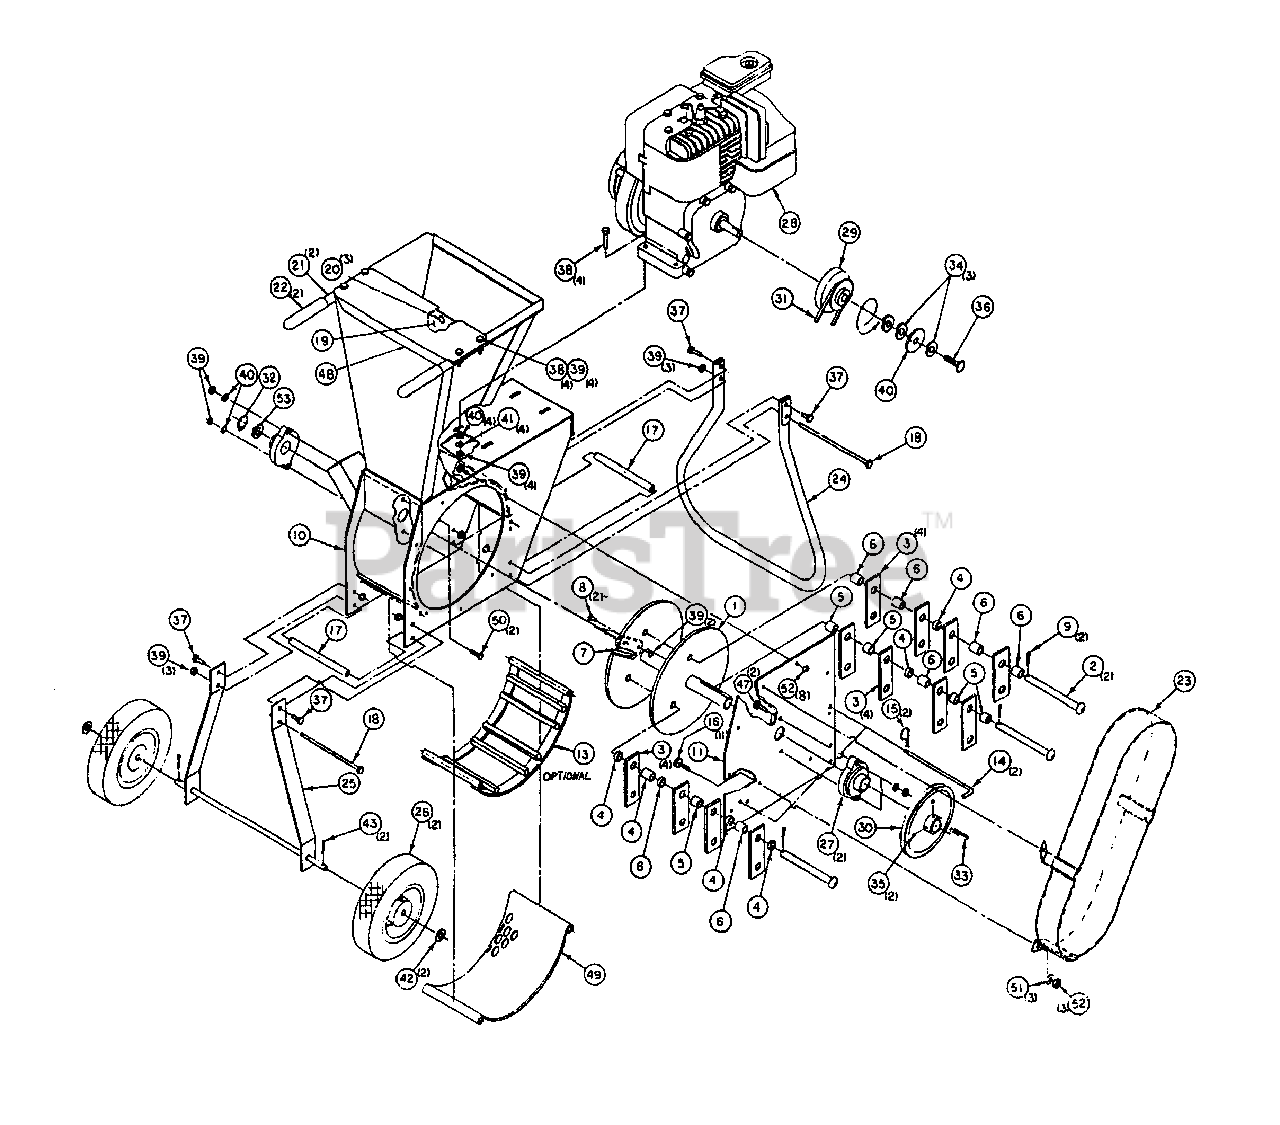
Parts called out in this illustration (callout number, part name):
1	Rotor Weldment
2	Hammer Rod
3	Hammer
4	Spacer 5/16" LG
5	Spacer 5/8" LG
6	Spacer 7/8" LG
7	Chipper Knife
8	5/16-18 x 1" Flat Hd. Socket Cap Screw
9	3/16" x 1-1/4" LG Cotter Pin
10	Main Body Assembly
11	Cover Plate
13	Bar Screen
14	Screen Rod
15	Hair Cotter 3/32"
16	1/4-20 x 5/8" Hex Hd. Cap Screw
17	Pipe Spacer
18	5/16-18 x 7-1/2" LG Hex Hd. Cap Screw
19	Hopper Flex Guard
20	Push Type Tie Button
21	Handle
22	Handle Grip
23	Belt Guard
24	Front Foot
25	Axle Assembly
26	8 x 1.75 Wheel
27	Bearing
28	* ENGINE, 3 HP
29	Centrifugal Clutch
30	Sheave A550 x 1
31	V-Belt 4L-390
32	Retaining Ring
33	Shaft Key 1/4" x 1"
34	1/4" Split Lockwasher
35	5/16-18 x 5/16" Set Screw
36	1/4-28 x 3/4 Hex Hd. Cap Screw
37	5/16-18 x 3/4" Hex Hd. Cap Screw
38	5/16-18 x 1-1/2" Hex Hd. Cap Screw
39	5/16-18 Grip-Co Lock Nut
40	5/16" Flatwasher
41	5/16" Internal Lockwasher
42	1/2" Flatwasher
43	1/8 x 1-1/4" Cotter Pin
47	5/16-18 x 1" Hex Hd. Cap Screw
48	Hopper Lid
49	1" Screen
50	5/16-18 x 1" Milled Hd. Cap Screw
51	1/4" Flat Washer
52	1/4-20 Flex Lock Nuts Cap Pltd.
53	1 1/2" O.D. x 1 1/64" I.D. x .050 Thk Shim
